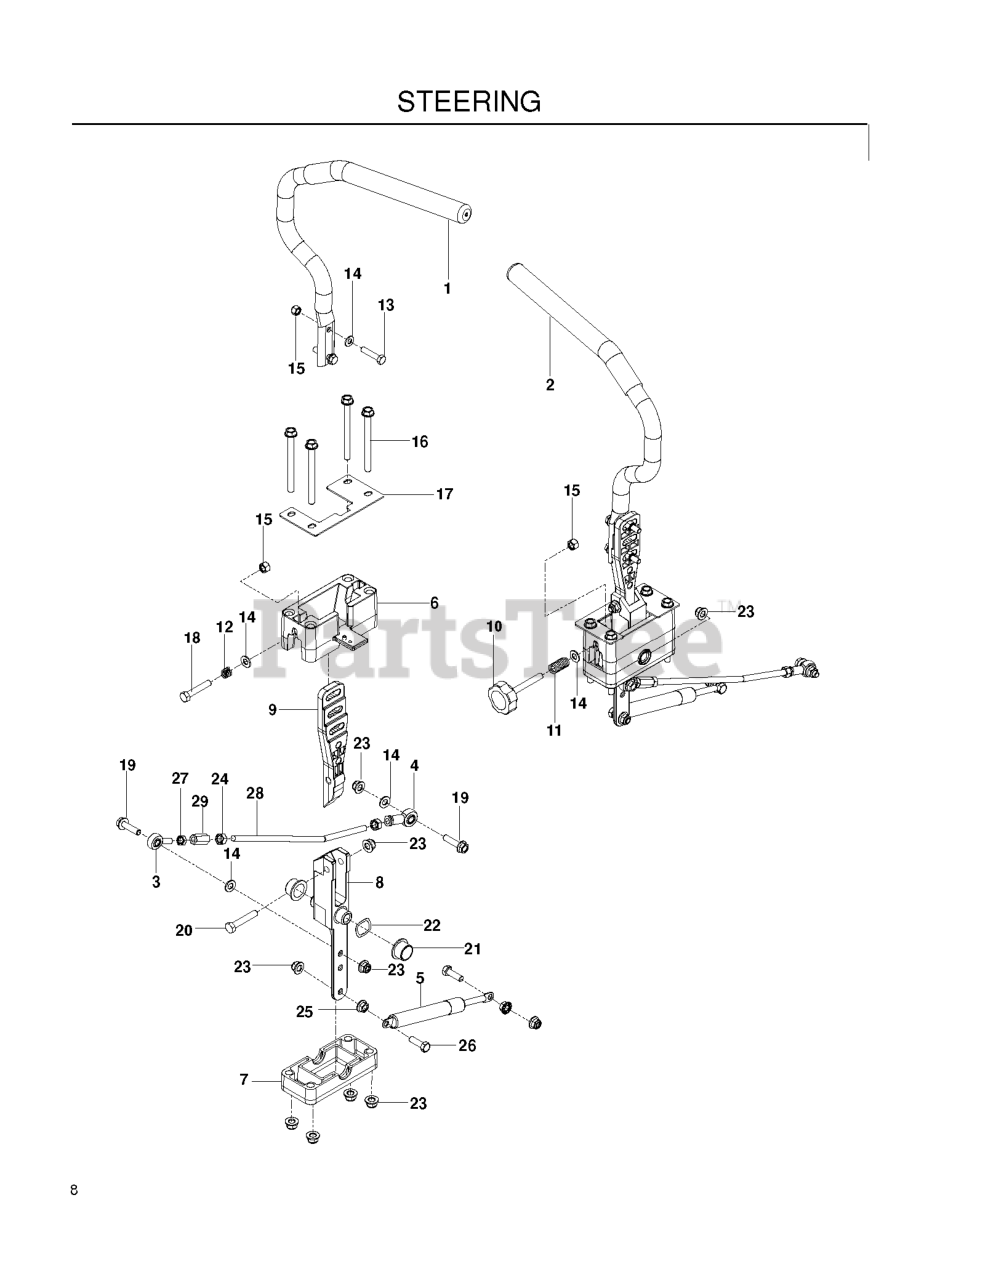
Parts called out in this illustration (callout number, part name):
1	LEVER.DRIVE.W/GRIP.RIGHT
2	LEVER.DRIVE.W/GRIP.LEFT
3	RP.ROD.END.LH
4	RH ROD END
6	BLOCK, UPPER
7	BLOCK, LOWER
8	PIVOT.SECTION.DRIVE.CONTROL
9	MOUNT, DR CNTRL HANDLE
13	CAPSCREW 5/16 X 1/1/2 HEX HEAD
14	FLAT WASHER 5/16 SAE
15	NUT 5/16 NYLOC
16	HHFS 5/16-18 X 3 3/4
17	PLATE, NEUTRAL STOP, BLACK
18	HCS 5/16-18X1-3/4 TPBLT
19	HHFS 5/16-18 X 1.25 TPBLT GD 5
20	HCS 5/16C X 1 3/4
21	BEARING, FLANGE
22	WASHER, .825 X 1.087, WAVE
23	5/16-18 NYLOC FLANGE NUT
25	NUT 5/16C WHIZ
26	HCS 5/16C X 1
27	NUT 5/16F LEFTHAND
28	ROD, CONTROL
29	ROD END COUPLER
